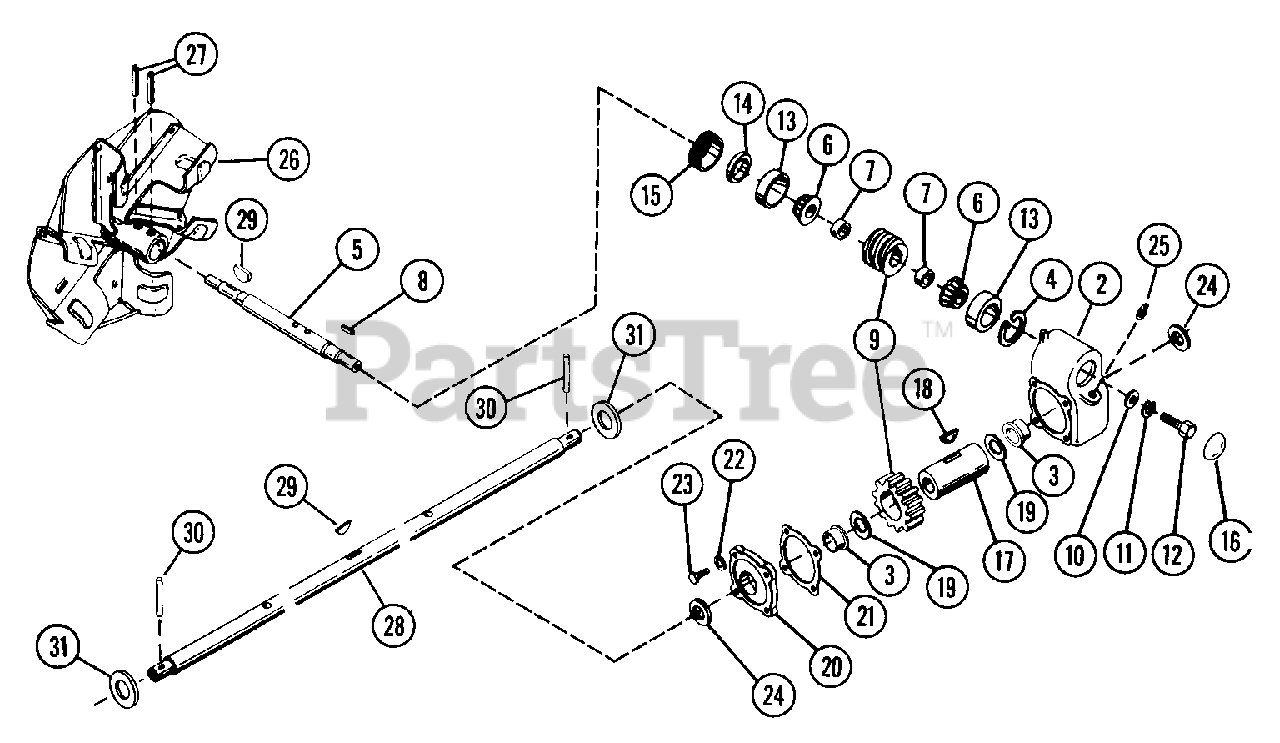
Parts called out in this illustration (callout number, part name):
1	GEAR CASE - CAST IRON
2	GEAR CASE - CAST IRON
3	BSHG-FLG .683X1.87X1.68X2.250
4	RG-RTNG-INT 1.781X.062
5	SHAFT, WORM - 1.00 DIA.
6	BRG-CONE .750X.61
7	BSHG, SPCR .755X1.12X.50 PM
8	KEY-SQ .188X1.0X.188 SAE 8630
9	WORM & GEAR SERVICE ASSEMBLY
10	WSHR-FL-STL .328X1.0X.094
11	WSHR-LK .312X.097 PL HVY
12	BLT-HEX .31-18X.75 PL GR2
13	BRG-CUP 1.781X.475
14	SEAL 1.000X1.312X.150
15	ADJUSTMENT PLUG - 1" SHAFT
16	DUST CAP
17	GEAR CASE SHAFT
18	KEY-WDRF .25X.875X.375 SAE A
19	WSHR-FL-STL 1.625X2.500X.012
20	GEAR CASE COVER
22	WSHR-LK-EXT. 250 ID
23	BLT-HEX .25-20X.75 PL GR2
24	SEAL 1.625X2.125X.250
25	PIPE PLUG
26	FAN - 14"
27	PIN-ROLL .313X1.75
28	SHAFT, 36" RAKE - 1.00 DIA.
28	SHAFT, 32" RAKE - 1.00 DIA.
29	KEY-WDRF .188X.875X.375 SAE11
30	PIN-ROLL .188X1.50
31	WSHR-FL-STL 1.010X1.505X.062PL
